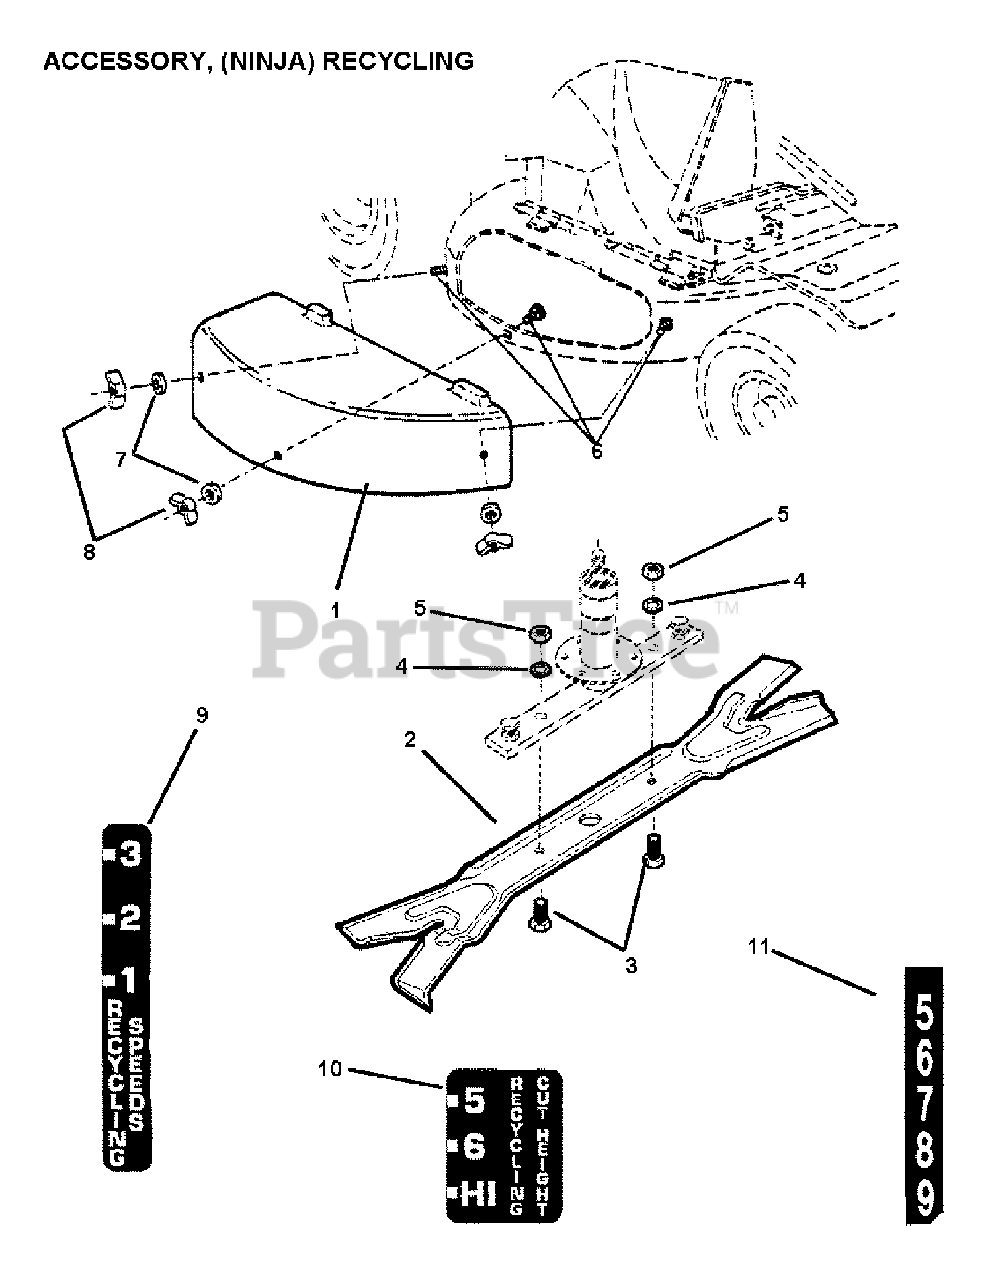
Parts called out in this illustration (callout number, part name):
1	COVER, Side Chute (33" Models)
2	BLADE, 33" Ninja (Quad Edge)
3	SCREW, 1/2-20 x 1" Hex Head Cap (Grade 5)
4	WASHER, 1/2" Internal Tooth Lock
5	NUT, 1/2-20 Hex Jam
6	BOLT, 5/16-18 x 3/4" Short Neck Carriage (Grade 5)
7	WASHER, 5/16" Flat
8	NUT, 5/16-18 Wing
9	DECAL, Recycling Ground Speeds
10	DECAL, Recycling Height of Cut
11	DECAL, Cut Height
